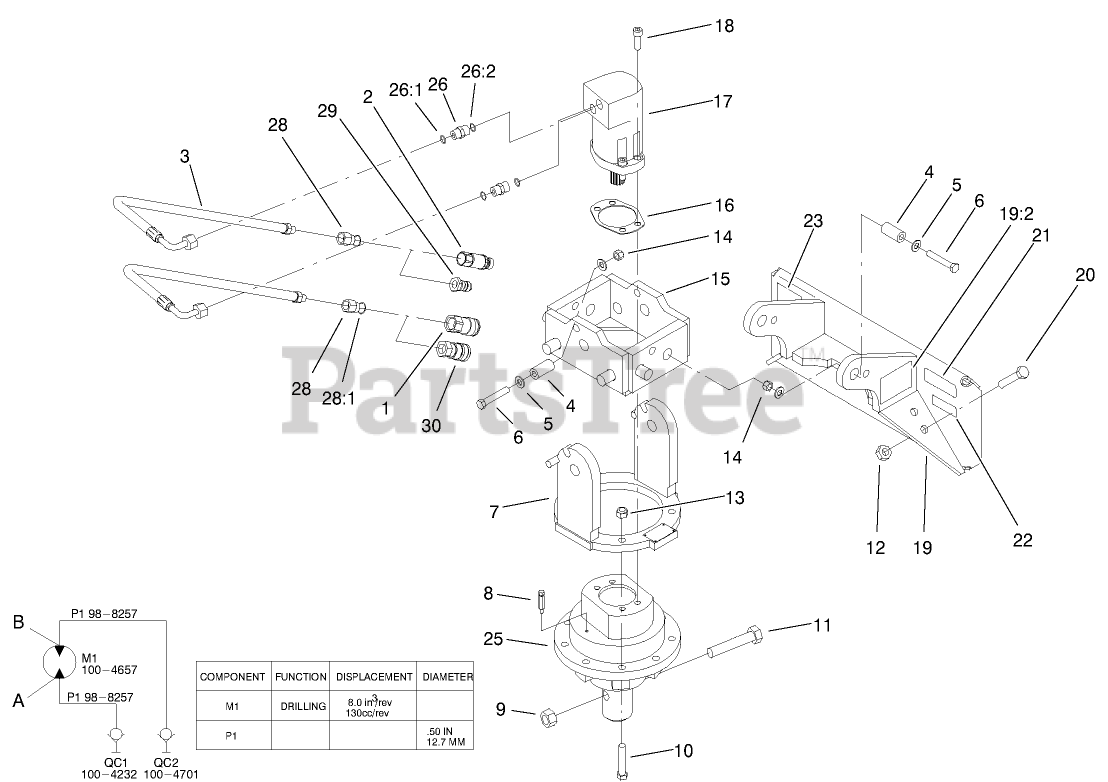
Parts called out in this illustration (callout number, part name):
1	COUPLER-FACE, FLUSH
2	NIPPLE-CONNECT, PRESSURE
3	HOSE - HYDRAULIC
4	PIN - PIVOT
5	WASHER-FLAT
6	SCREW-HH
7	HOUSING - DRIVE
8	BREATHER ASM
9	NUT-HEX
10	SCREW-HH
11	SCREW
12	NUT-HEX
13	LOCKNUT
14	NUT-LOCK, NI
15	SWIVEL GIMBEL ASM
16	GASKET
17	HYDRAULIC MOTOR ASM
18	SCREW-HSH
19	AUGER MOUNT ASM,
19:2	DECAL-WARNING
20	SCREW-HH
21	DECAL-ATTACHMENT, DINGO
22	DECAL-INFO
23	DECAL
25	DRIVE-GEAR, PLANETARY
26	FITTING-STRAIGHT
26:1	O-RING
26:2	O-RING
28	ADAPTER-HYD
28:1	O-RING
29	DISCONNECT-QUICK, MALE
30	DISCONNECT-QUICK, FEMALE
